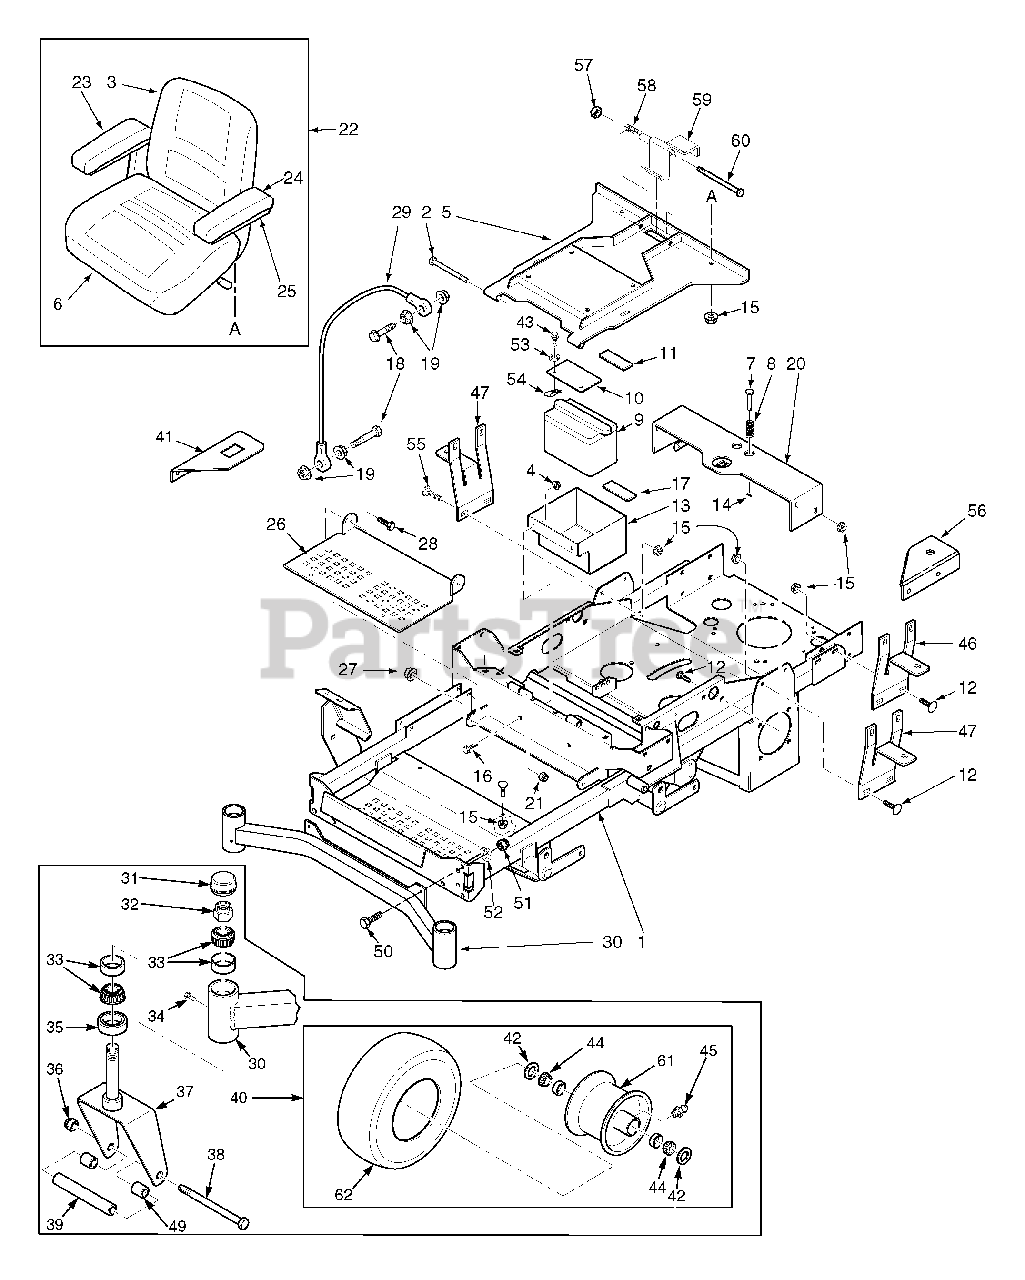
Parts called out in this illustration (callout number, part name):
1	Main Frame Assembly w/decals
2	Bolt, Hex Head 5/16-18 x 3-3/4"
3	Cushion, Back
4	Nut, Serr. Flange 3/8-16
5	Plate, Seat Mounting w/decals
6	Cushion, Lower Seat
7	Pin Retainer, Spring
8	Spring
9	Battery
10	Battery Cover
11	Battery Hold Down Pad
12	Bolt, Carr. 5/16-18 x 3/4"
13	Battery Box
14	Roll Pin, Spring 5/32 x 3/4"
15	Nut, Serr. Flange 5/16-18
16	Bolt, Hex Head 3/8-16 x 1"
17	Pad, Rubber
18	Bolt, Hex Head 1/4-20 x 1-1/4"
19	Nut, Serr. Flange 1/4-20
20	Seat Base Support
21	Nut, Elastic Stop 5/16-18
22	Seat Assembly w/ adj. rails
23	Arm Pad, RH
24	Arm Pad, LH
25	Channel, Armrest
26	Footplate
27	Nut, Elastic Stop 3/8-16
28	Bolt, Hex Head 3/8-16 x 1"
29	Cable, Seat Stop
30	Weldment, Caster Support
31	Cap, Grease
32	Nut, Elastic Stop 1.0-14
33	Bearing Set
34	Plug, 1/4-28
35	Seal, 2.0" OD x 1.625" ID
36	Nut, Elastic Stop 1/2-13
37	Yoke, Front Caster Wheel
38	Bolt, Hex Head 1/2-13 x 7-1/2"
39	Sleeve - 48" & 52"
40	Caster Wheel Assembly
41	Bracket, Hour Meter
43	Bolt, Hex Head 3/8-16 x 1-1/4"
44	Roller Bearing
45	Fitting, Grease
46	Mounting Bracket, Oil Tank
47	Mounting Bracket, Fuel Tank
48	Seat Pan
49	Spacer, Caster Wheel
50	Bolt, Hex Head 7/16-14 x 1-1/4"
51	Nut, Elastic Stop 7/16-14
52	Lockwasher, 7/16
53	Lock Washer. 3/8 Spring
54	U-Nut, 3/8-16
55	Bolt, Carriage 5/16-18 x 1"
56	Bracket, Fuel Valve
57	Lock Nut, 3/8-16 Center Lock
58	Spring, Seat Latch
59	Seat Latch Weldment
60	Bolt, Hex Head 3/8-16 x 6"
61	Rim 48" & 52"
62	Tire, 13 x 5.0-6 Smooth - 48" & 52"
